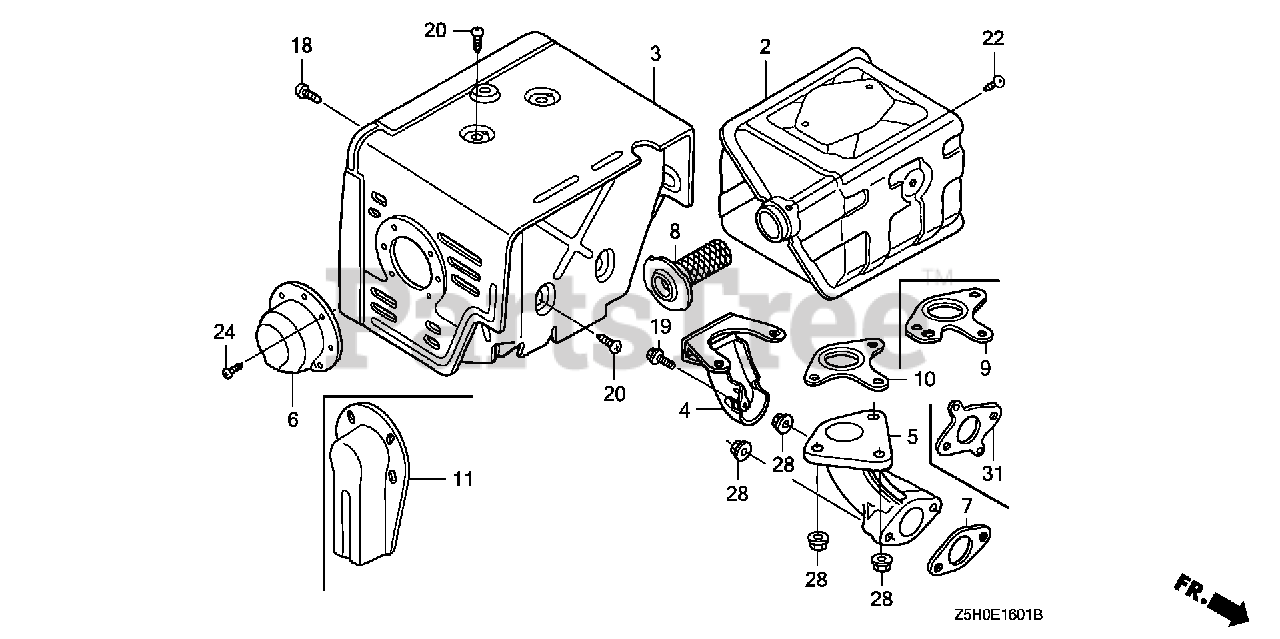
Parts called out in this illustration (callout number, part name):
2	MUFFLER (100DB)
3	PROTECTOR, MUFFLER
6	CAP, MUFFLER
8	ARRESTER, SPARK
9	GASKET, MUFFLER (ARRESTER)
9	GASKET, MUFFLER (ARRESTER)(THAI LEAKLESS)
11	DEFLECTOR, MUFFLER
18	SCREW, TAPPING (6X10)
20	SCREW, TAPPING (5X8)
22	SCREW, TAPPING (5X8)
22	SCREW, TAPPING (4X6) (TO INSTALL OPTIONAL SPARK ARRESTER)
24	SCREW, TAPPING (4X6) (TO INSTALL OPTIONAL SPARK ARRESTER)
28	NUT, FLANGE (8MM)
31	GASKET, EX. PIPE
